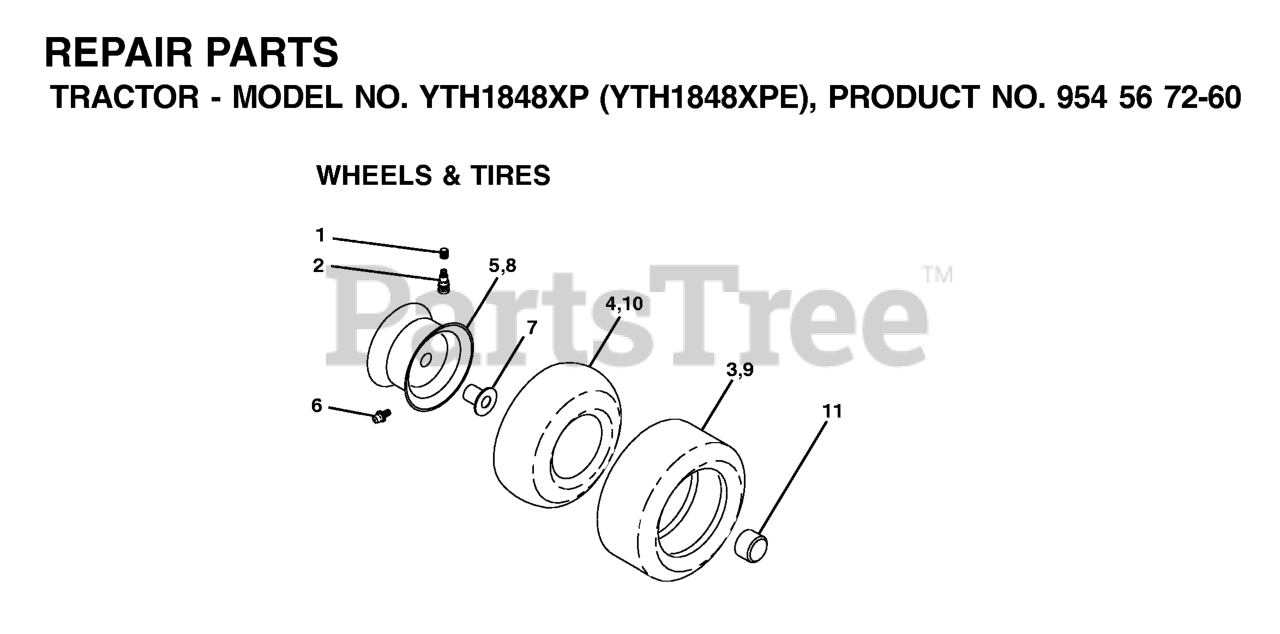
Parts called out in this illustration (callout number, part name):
2	VALVE STEM LT
3	TIRE HEAVY DUTY
4	TUBE.5.3/4.5/6
5	RIM ASM 6" FRONT SILVER
6	FITTING LT
7	BEARING T
8	RIM ASM 8" REAR SILVER
9	TIRE.TS.20X10-8
10	TUBE
11	CAP, AXLE BLK
